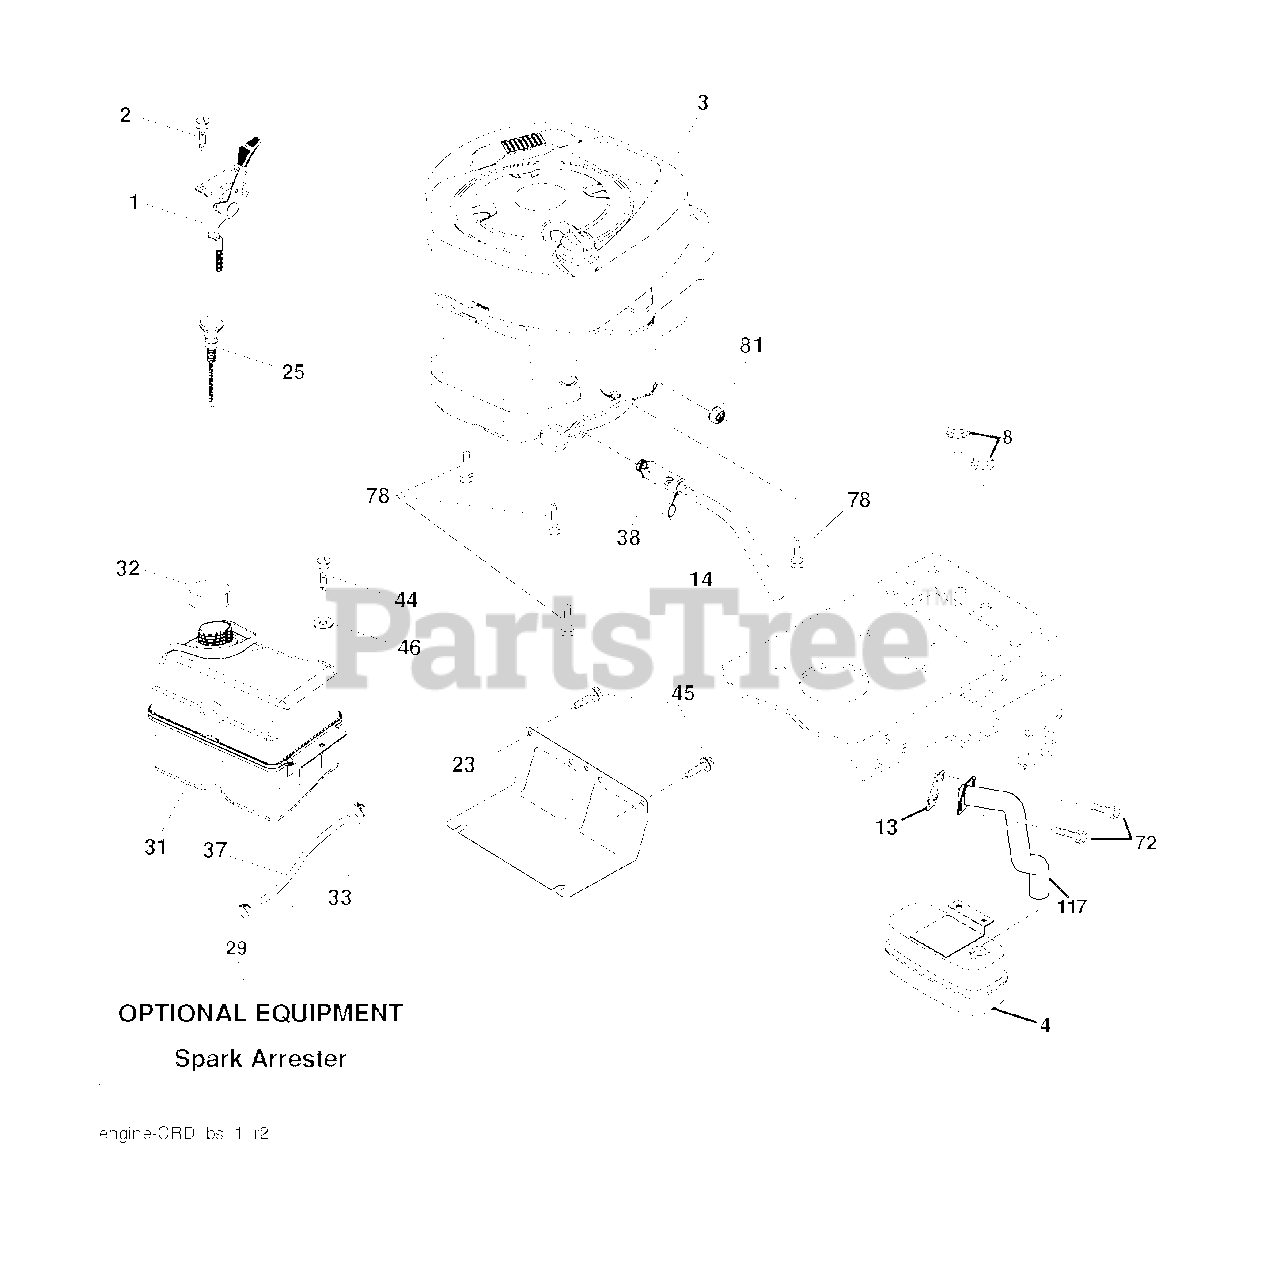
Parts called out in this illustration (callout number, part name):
1	CONTROL TH/CH FLAG
2	SCREW
4	MUFFLER.SINGLE.CYL.KOHL/B&S
8	BOLT, 5/16-18 X 1 3/4
13	REPL BY 532 27 22-93
23	SHEILD.BROWNING.DBR.GUARD
29	ARRESTER SPARK (OPTIONAL)
32	FUEL CAP
33	HOSE CLAMP
37	LINE.FUEL.20
44	SCREW HEXWSHR 1/4-20X3/4
45	SCREW, 3/8-16X3/4
72	SCREW.SOCKET HD.5/16-1
78	SCREW.3/8-16
81	NUT
117	EXHAUST.TUBE.B&S.
